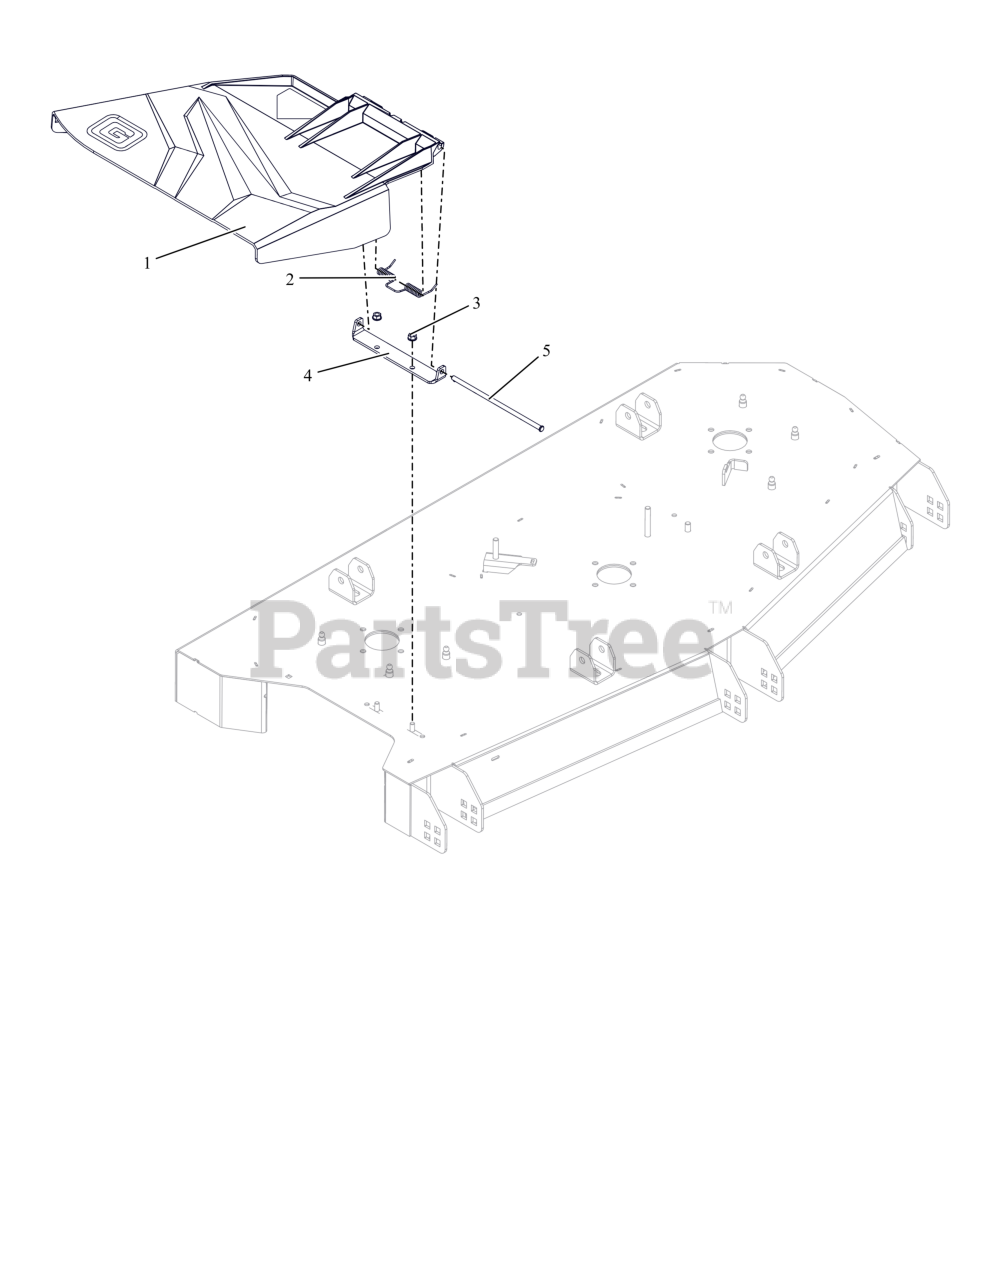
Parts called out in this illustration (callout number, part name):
1	CHUTE- SIDE DISCHARGE
2	SPRING-TORSION
3	NUT,LK-CTR-FLG .31-18 GF ZCC
4	BRKT- DISCHARGE CHUTE-GRAVELY
5	PIN, SLIC-.312X10.45
